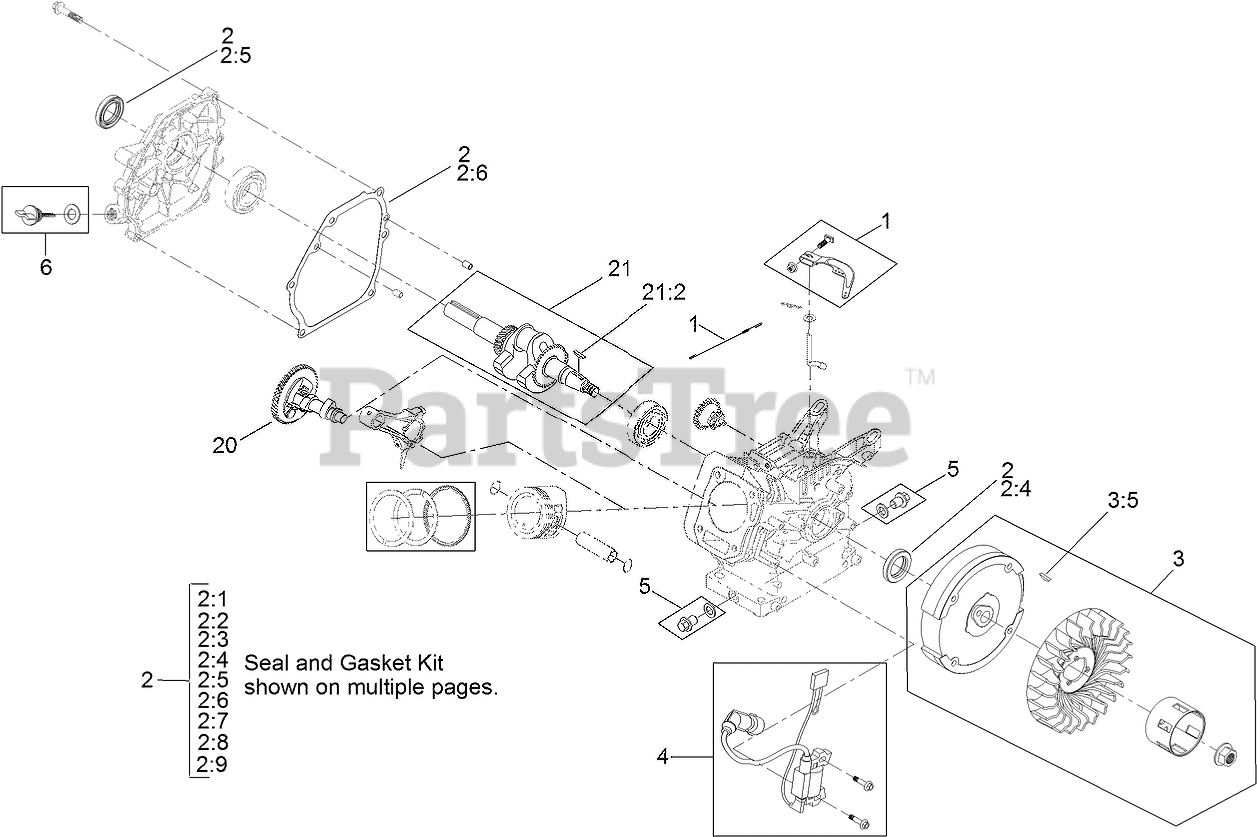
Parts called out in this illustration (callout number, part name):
1	GOVERNOR KIT
2	GASKET AND SEAL KIT
2:1	GASKET-COVER, VALVE
2:2	GASKET-EXHAUST
2:3	GASKET-HEAD, CYLINDER
2:5	SEAL-OIL
2:6	GASKET-COVER, CRANKCASE
2:7	GASKET-CARBURETOR
2:8	GASKET-CARBURETOR
2:9	GASKET-CARBURETOR
3	RECOIL FLYWHEEL KIT
3:5	KEY-WOODRUFF
4	IGNITION KIT
5	DRAIN PLUG KIT
6	DIPSTICK AND O-RING KIT
20	CAMSHAFT
21	Loose Parts Package
21:2	KEY-WOODRUFF
